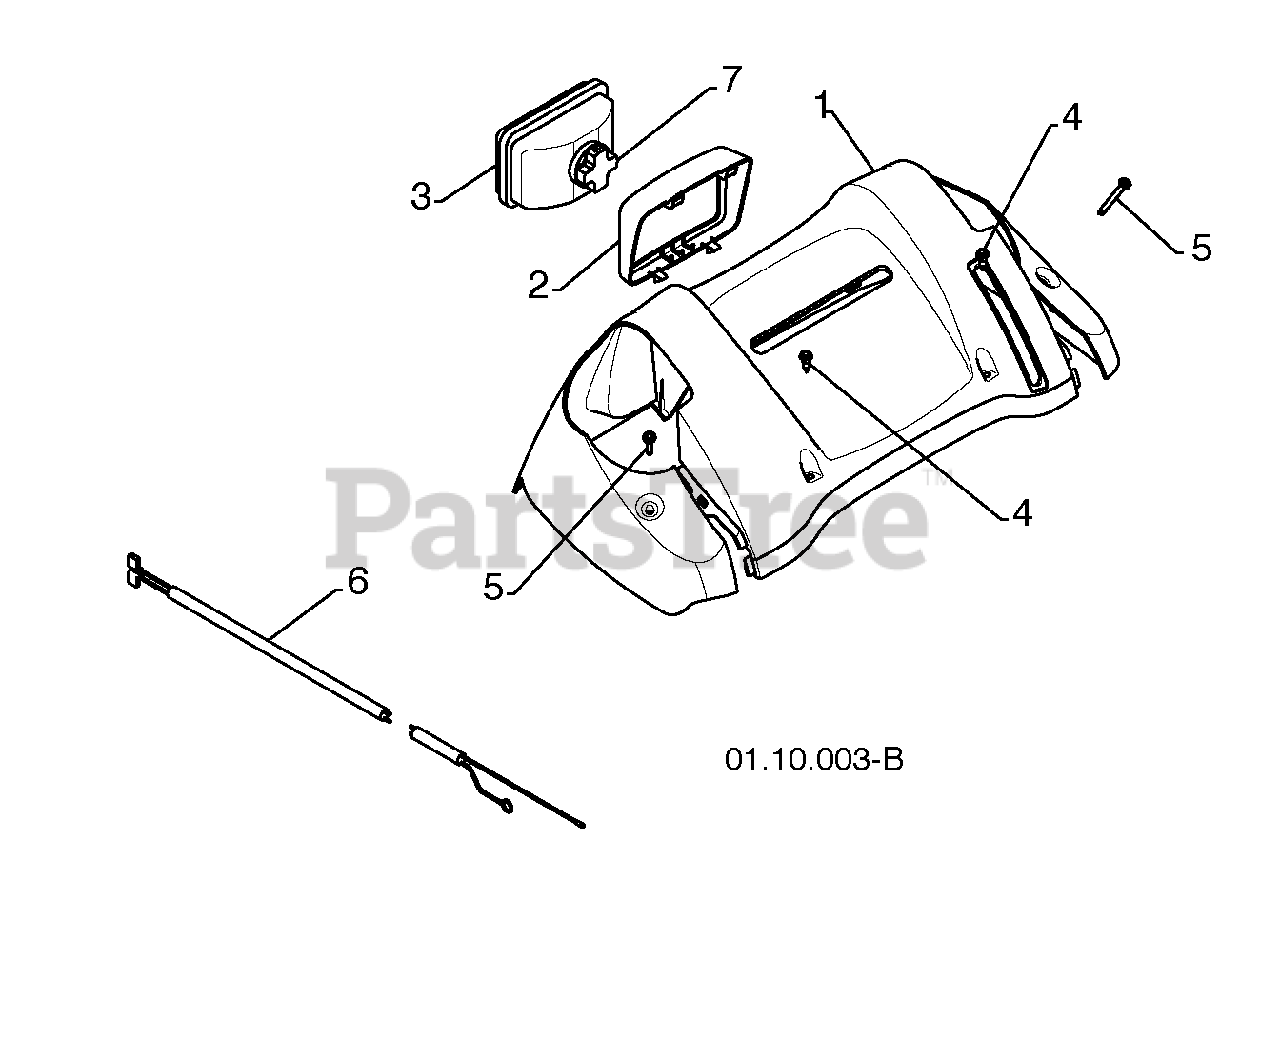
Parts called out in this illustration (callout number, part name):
1	CONSOLE PANEL
2	HEADLIGHT BEZEL
3	FLOOD HEADLIGHT
4	SHOULDER SCREW 10-24 X .625
5	SCREW 10-24 X 1.25
6	WIRE HARNESS
7	BULB
